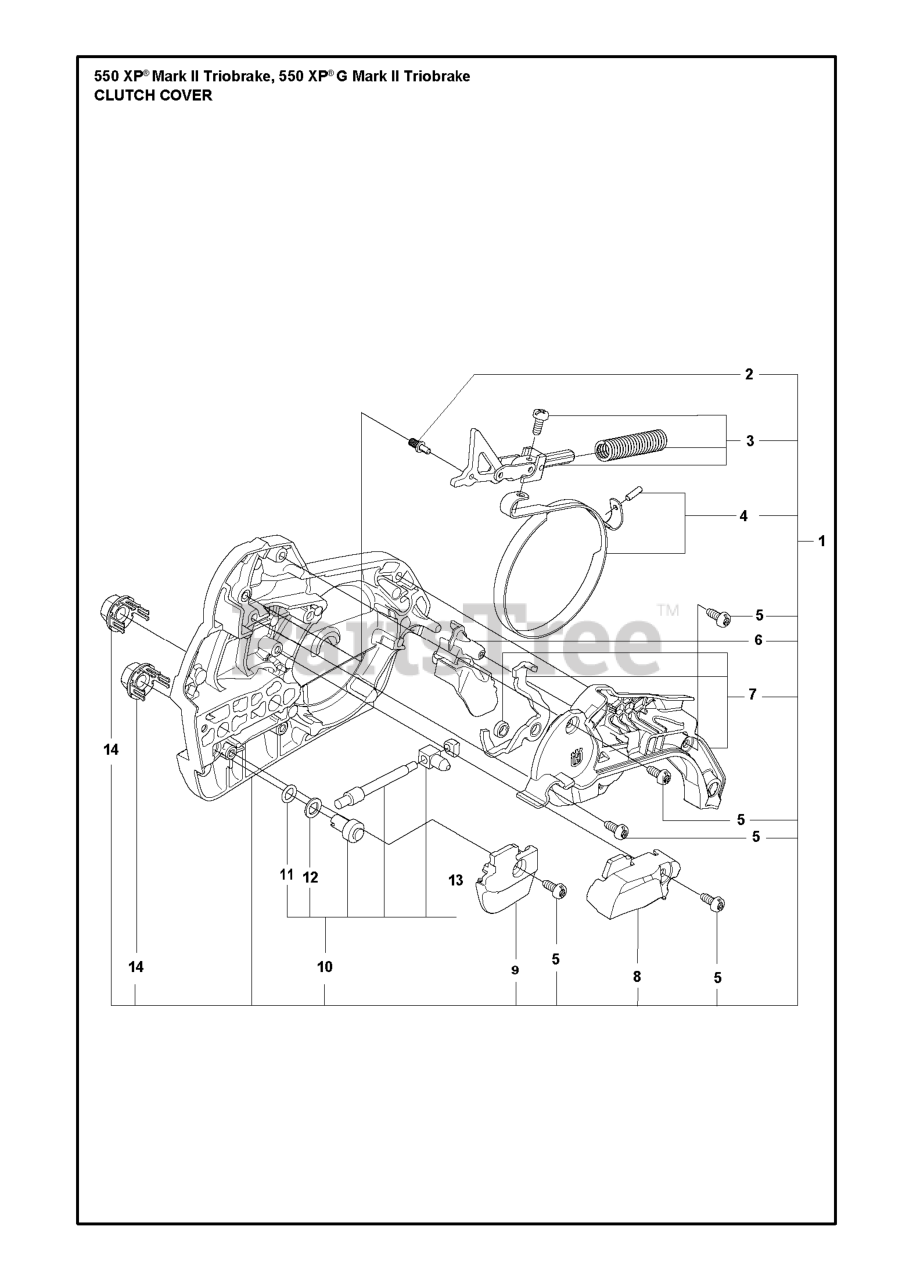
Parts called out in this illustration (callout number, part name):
3	KNEE JOINT ASSY KIT 50CC MARK
4	BRAKE BAND
7	COVER LID ASSY
8	CHAIN GUIDE UPPER
9	CHAIN GUIDE
10	CHAIN TENSIONER KIT
14	NUT RETAINER ASSY
